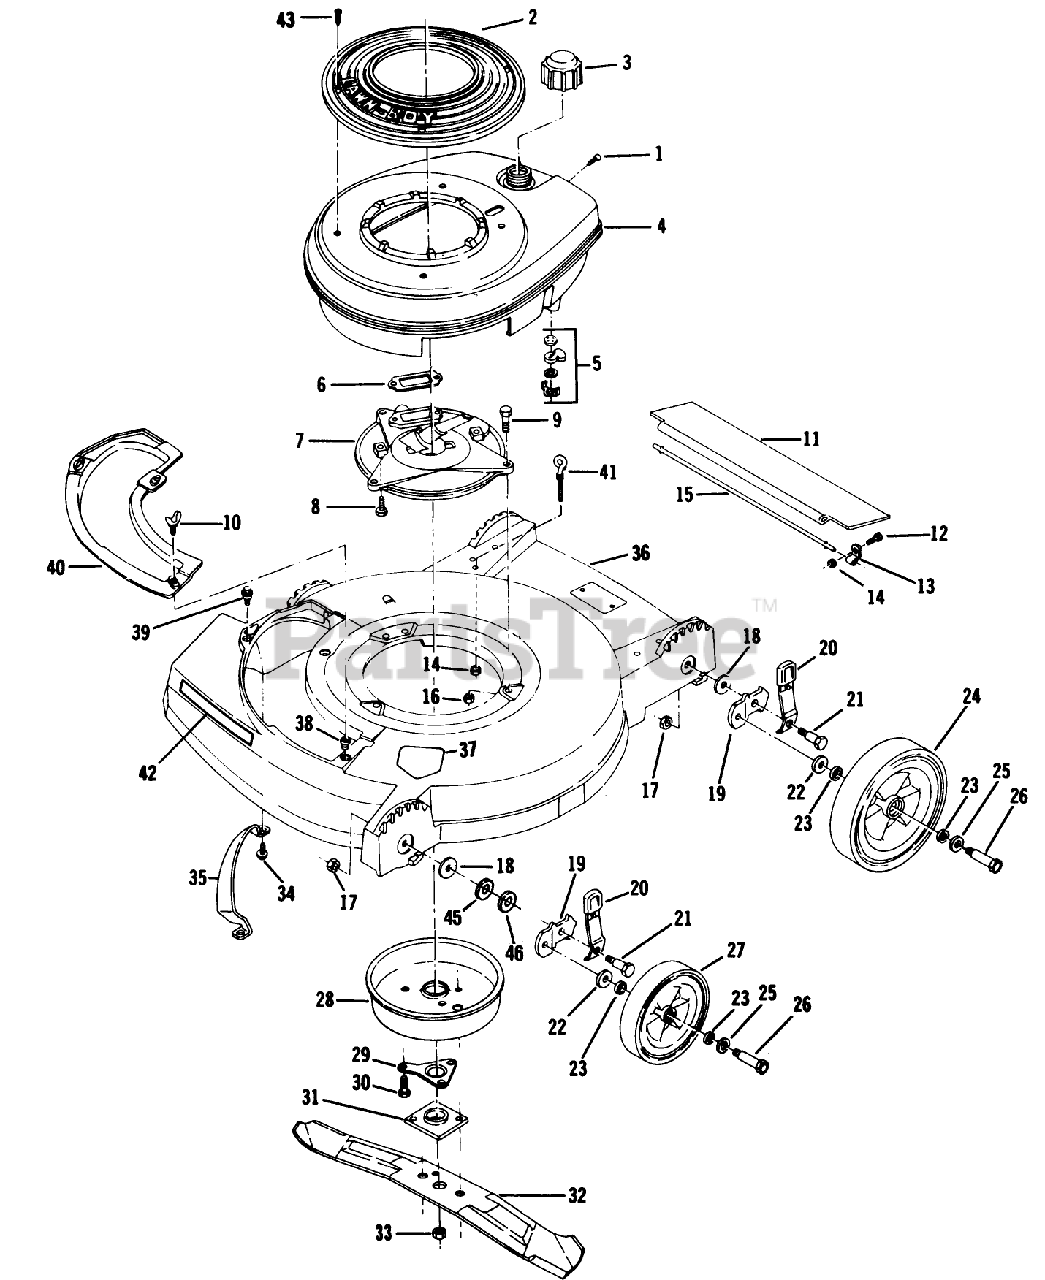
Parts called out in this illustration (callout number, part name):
1	SCREW - SELF TAPPING
3	FUEL CAP & INSERT
5	SHUT OFF VALVE KIT
8	SCREW V
9	SCREW-HH
10	WING SCREW LAWRE
13	CLAMP ROD KMC
14	LOCKNUT E
15	ROD 21" ADVANCE
16	NUT-LOCK F
17	LOCKNUT
18	WASHER
20	SPRING ARM ASM
21	BOLT
22	WASHER WROUGHT
23	WASHER
25	SPACER
26	BOLT WHEEL
27	WHEEL & TIRE KIT
28	MUFFLER COVER F
29	SUPPORT F
30	SCREW
31	PLATE AND COLLAR ASM
33	NUT-BLADE
35	BAR-TOE
41	BOLT-EYE
43	SCREW - SELF TAPPING
45	WASHER
46	WASHER
